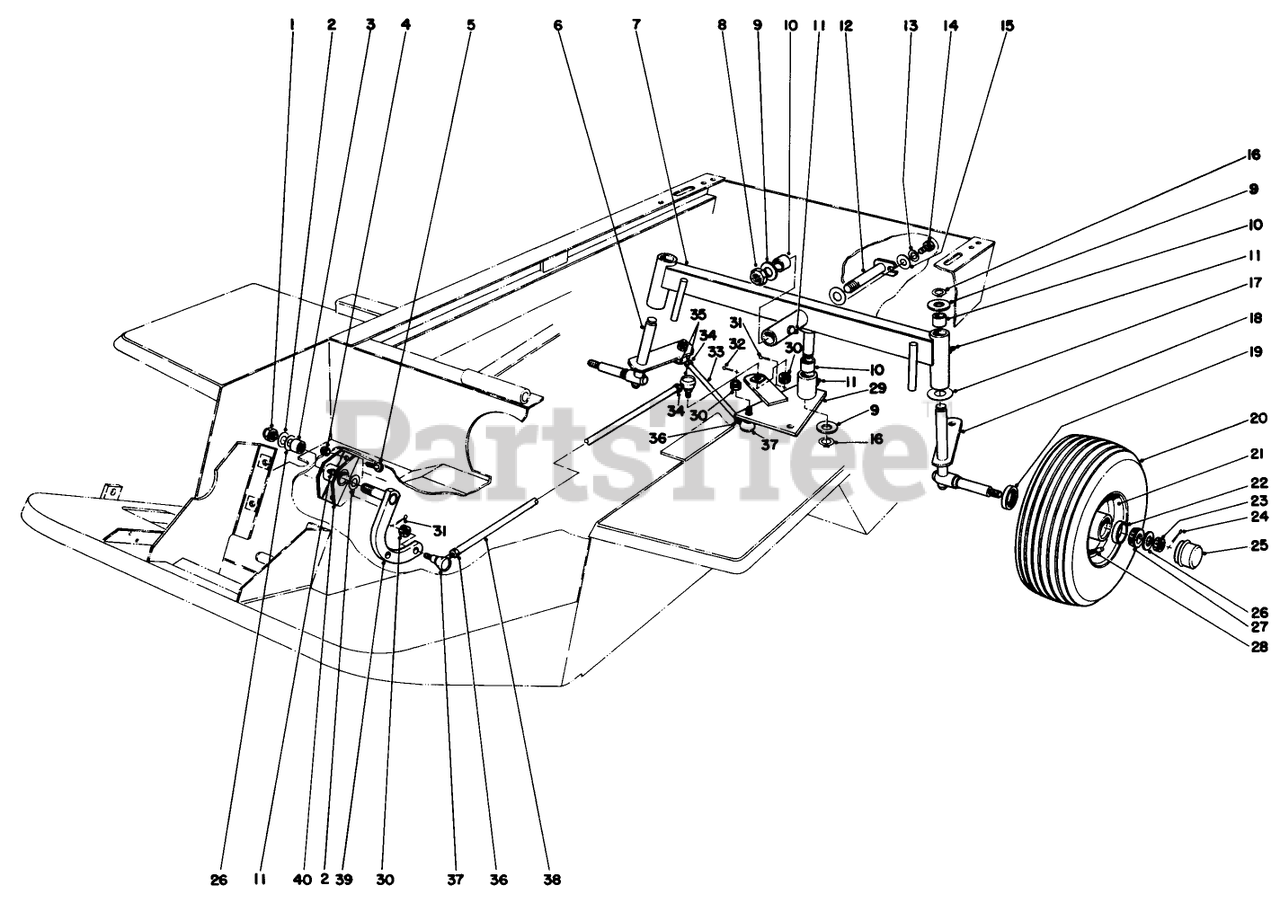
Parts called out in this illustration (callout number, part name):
1	NUT-LOCK, NI
2	THRUST WASHER
3	BEARING-NEEDLE
4	NUT-LOCK, NI
5	SCREW-HH
7	REAR AXLE WA
8	NUT-LOCK, NI
11	FITTING-GREASE
13	SCREW-HH
14	SCREW-HH
15	WASHER-FLAT
16	RING-RETAINING
17	WASHER-THRUST
22	BEARING-CUP, TAPERED
23	NUT-HEX, SLOTTED
24	PIN-COTTER
25	CAP-DUST
26	WASHER-FLAT
27	BEARING-CONE, TAPERED
30	NUT-HEX,SLOTTED
32	SCREW-HH
34	NUT-HEX JAM LH
36	NUT-JAM
38	REAR STRG TUBE *PP
39	PIVOT ARM WA
